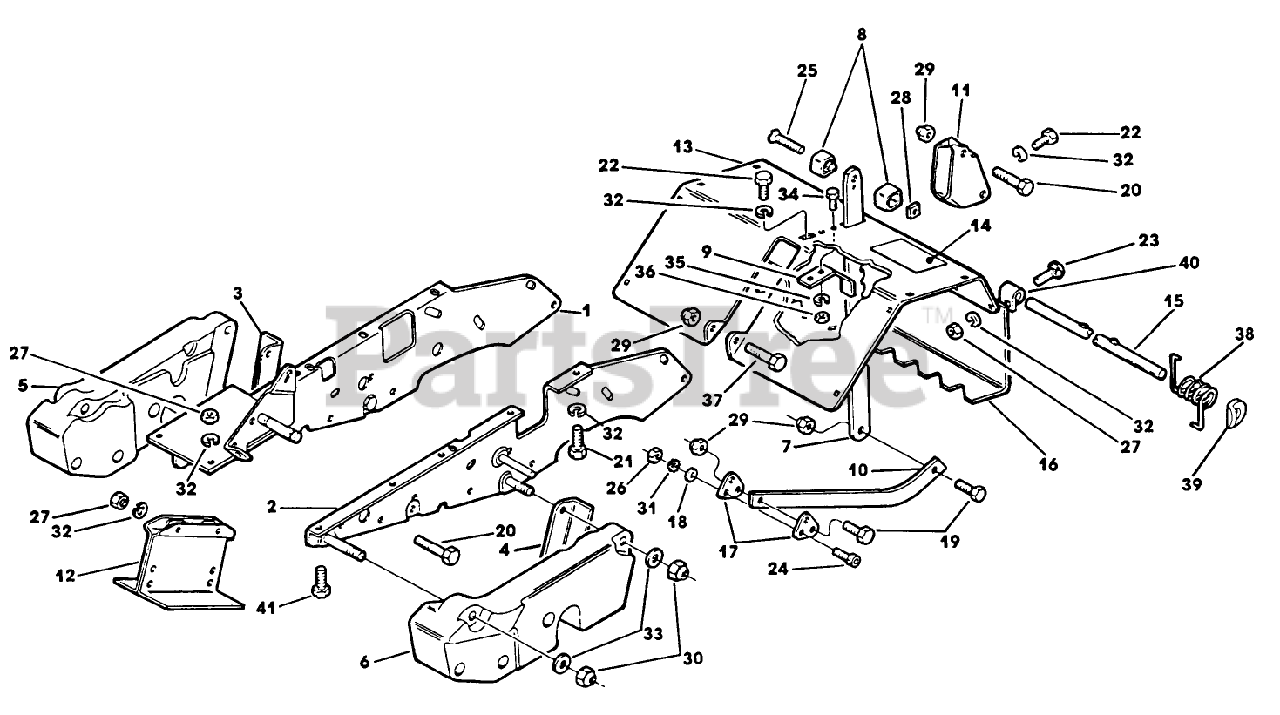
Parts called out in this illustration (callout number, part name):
23	BOLT - CARRIAGE
27	NUT SS
29	NUT
30	NUT-LOCKING
33	WASHER
34	SCREW-HH
36	NUT
41	SCREW - HEX
